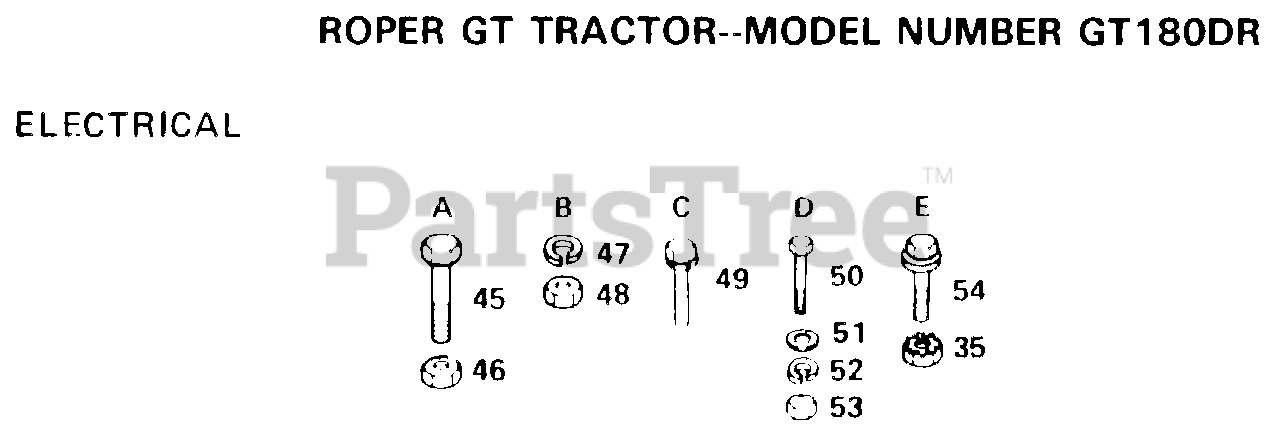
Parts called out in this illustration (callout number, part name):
35	"NUT,KEPS"
45	BOLT
48	NUT
49	SCREW ST
50	BOLT LT
51	WASHER
52	LOCKWASHER
54	SCREW
